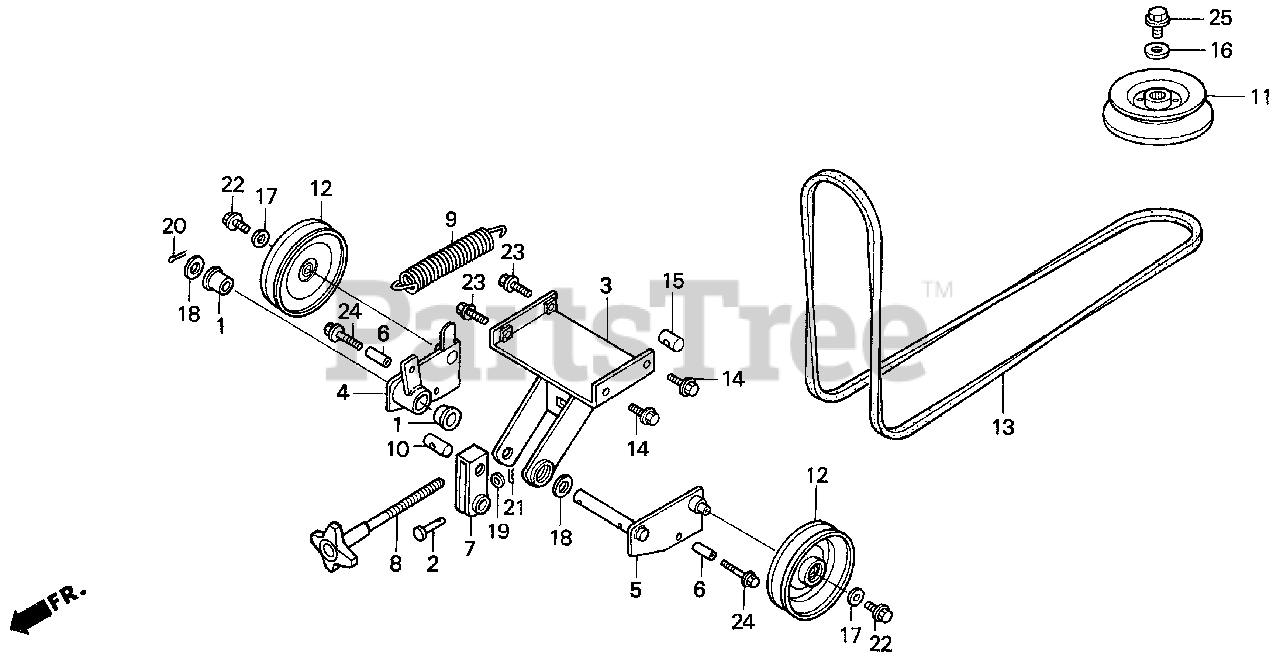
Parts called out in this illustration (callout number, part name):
1	BUSH, BRAKE PEDAL
2	PIN, STEP BAR JOINT
3	BRACKET, TENSIONER
4	ARM A, TENSIONER
5	ARM B, TENSIONER
6	COLLAR, BELT STOPPER
7	LEVER, TENSIONER
8	KNOB, TENSIONER
9	SPRING, TENSIONER
10	PIN, TENSIONER
12	PULLEY, IDLER
13	V-BELT, DECK (LB-99)
14	BOLT, TENSIONER BRACKET (8MM)
15	NUT, TENSIONER
17	WASHER (6MM)
18	WASHER, PLAIN (20MM)
19	WASHER, PLAIN (8MM)
20	PIN, COTTER (4.0X40)
21	PIN, LOCK (8MM)
22	BOLT, FLANGE (6X12)
23	BOLT, FLANGE (8X16)
24	BOLT, FLANGE (8X45)
